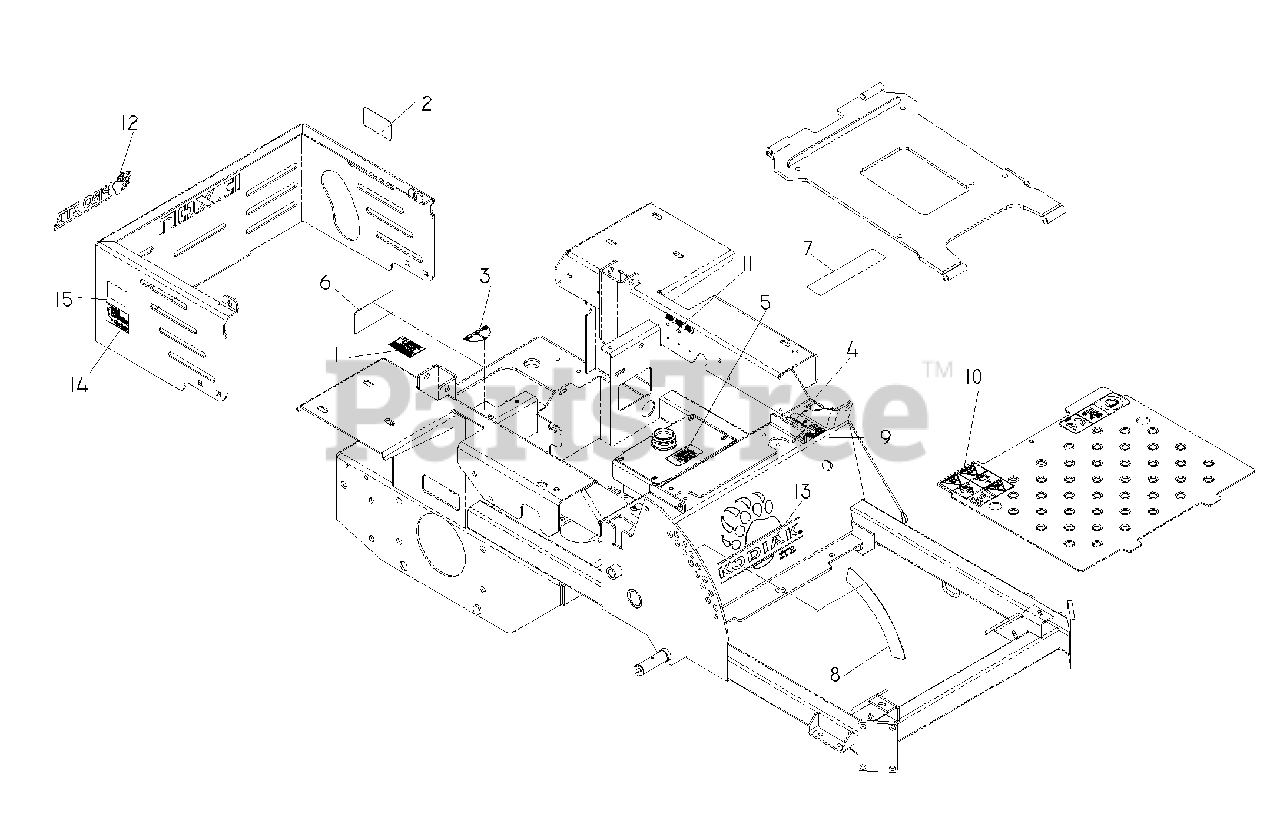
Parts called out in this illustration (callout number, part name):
1	DECAL, EXHAUST
2	DECAL, PROP. 65
3	DECAL, FUEL VALVE
4	DECAL, MOTION CONTROL
5	DECAL, OIL TANK
6	DECAL, BELT DRIVE
7	DECAL, BATTERY
9	DECAL, F.S.T.
10	DECAL, WARNING
11	DECAL, RELAYS
12	DECAL, PRO ZTR
13	DECAL, KODIAK
14	DECAL, PARKER
15	DECAL, KOHLER
